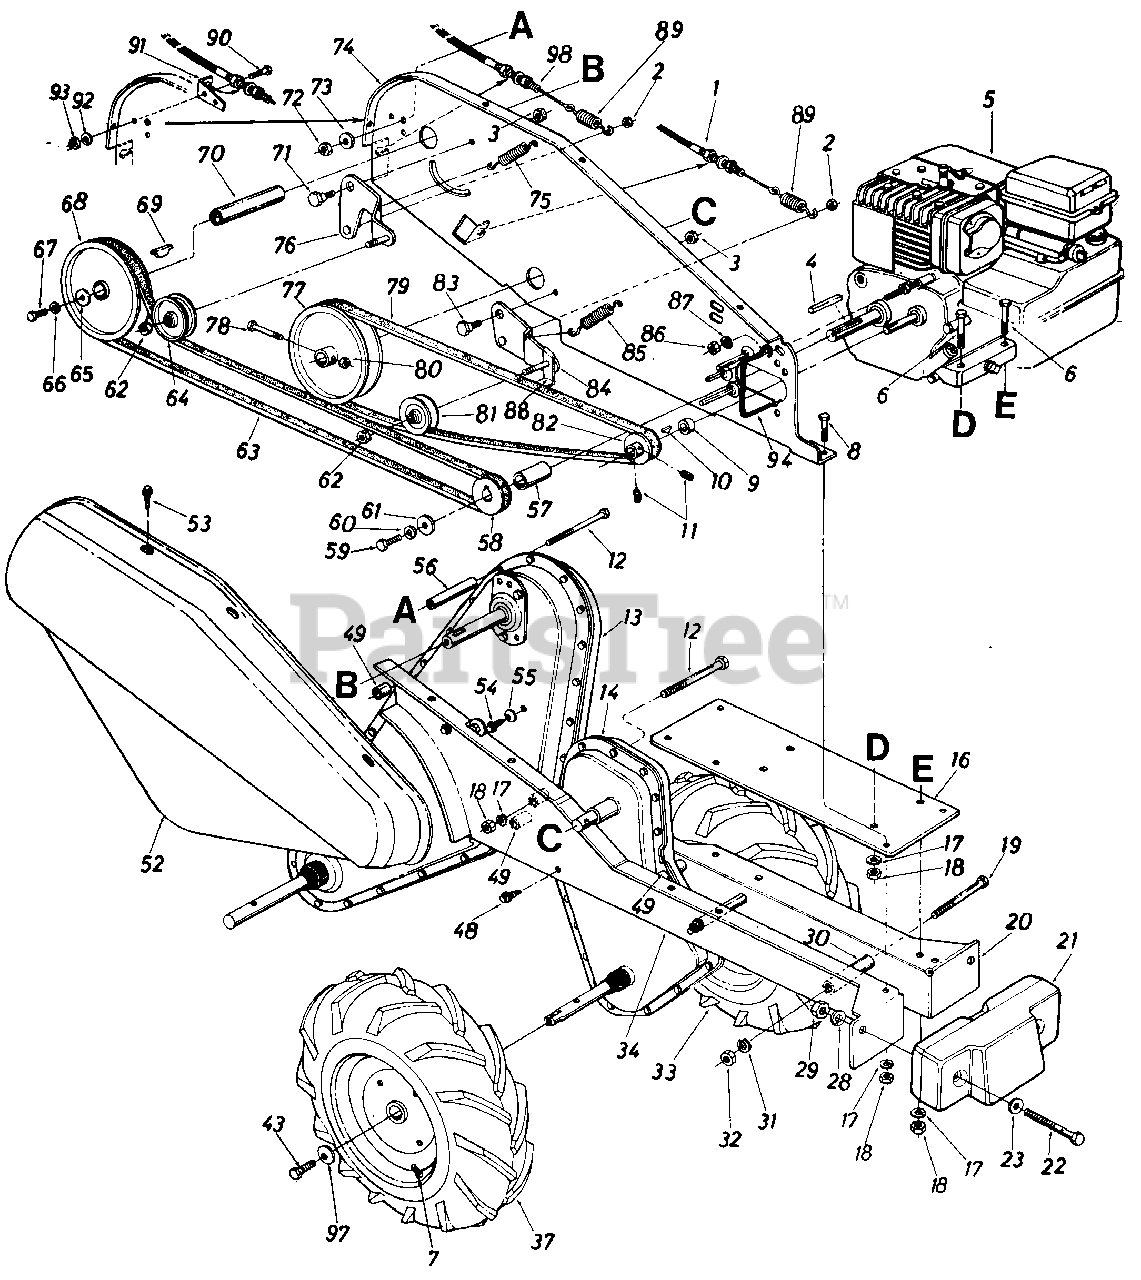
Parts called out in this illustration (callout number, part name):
1	Clutch Control Cable
2	Hex Cent. L-Nut 1/4-20 Thd.
3	Hex Cent. L-Nut 3/8-16 Thd.
4	Sq. Key 3/16" Dia. x .75
5	Engine
6	Hex Bolt 5/16-18 x 1.50" Lg.
7	Air Valve
8	Hex Bolt 5/16-18 x .75" Lg.
9	Spacer .51" l.D. x 3/4" O.D. x.39" Lg.
10	Hi-Pro Key #5 Woodruff
11	Set Scr. 1/4-28 x .25" Lg.
12	Hex Bolt 5/16-18 x 3.0" Lg.
18	Hex Nut 5/16-18 Thd.
19	Hex Bolt 3/8-24 x 3 on Lg.
22	Hex Bolt 1/2-13 x 4.0" Lg.
23	Fl-Wash. 1/2" l.D. x 1.0" O.D.
28	L-Wash. 1/2" l.D.
29	Hex Nut 1/2-13 Thd.
30	Spacer 3/8" l.D. x 5/8" O.D. x 2.18" Lg.
31	L-Wash. 3/8" l.D.
32	Hex Nut 3/8-24 Thd.
33	Comp. Wheel Ass'y.-L.H.
48	Hex Wash. Self-Tap Scr. 5/16-24 x .50" Lg.
49	Spacer 5/16" I.D. x 16 Ga. x.96" Lg.
54	Hex Wash. S-Tap Scr. 1/4-20 x 3/8" La.
55	Bell-Wash. 1/4" l.D.
56	Spacer 3/8" l.D. x 1/2" O.D. x 2.0" Lg.
57	Spacer 3/4" I.D. x 1.12" O.D. x 1.56" Lg.
58	1/2" "V"-4L Pulley 3/4" I.D. x 2.59" O.D.
59	Hex Bolt 5/16-24 x 1.0" Lg.
60	L-Wash. 5/16" l.D.
61	Fl-Wash. 5/16" l.D. x 1.25" O.D.
62	Hex L-Nut 3/8-24 Thd.
63	"V"-Belt
64	Fl-ldler Pulley 3.75" O.D. x 3/8" l.D.
65	Fl-Wash. .25" I.D. x .93 0 O.D. x .120
66	L-Wash. 1/4" l.D.
67	Hex Bolt 1/4-28 x 75" Lg.
68	Split Pulley 6" Dia. x 5/8" I.D.
69	Hi-Pro Key
71	Shld. Bolt l/2" Dia. x .210" Lg.
72	Hex Nut 5/16-18 Thd.
73	L-Wash. 5/16" l.D.
74	Side Plate Ass'y.
75	Ext. Spring 50" O.D. x l.55" Lg.
76	483Idler Bracket Ass'y.-Tines
77	Pulley 6" Dia. x 5/8" I.D.
78	Hex Bolt 1/4-28 x 1.50" Lg.
79	"V"-Belt
80	Hex Cent. L-Nut 1/4-28 Thd.'
81	"V"-ldler Pulley 2-5/8" O.D.
82	1/2" "V"-Pulley 21/4" O.D. x 50" l.D.
83	Shld. Bolt 1/2" Dia. x .160" Lg.
84	Idler Bracket Ass'y-Wheels
85	Ext. Spring 50" O.D. x 1.55" Lg
86	Hex Nut 1/4-20 Thd.
87	Bell-Wash. 1/4" I.D.
88	Belt Keeper Ass'y.
90	Hex Bolt 5/16-18 x .75"
91	Clutch Cable Brkt.
92	Lock Washer 5/16" I.D.
93	Hex Nut 5/16-18 Thd.
94	Belt Keeper
97	Bell-Wash. 5/16" l.D.
98	Clu,ch Control Cable rTines)
